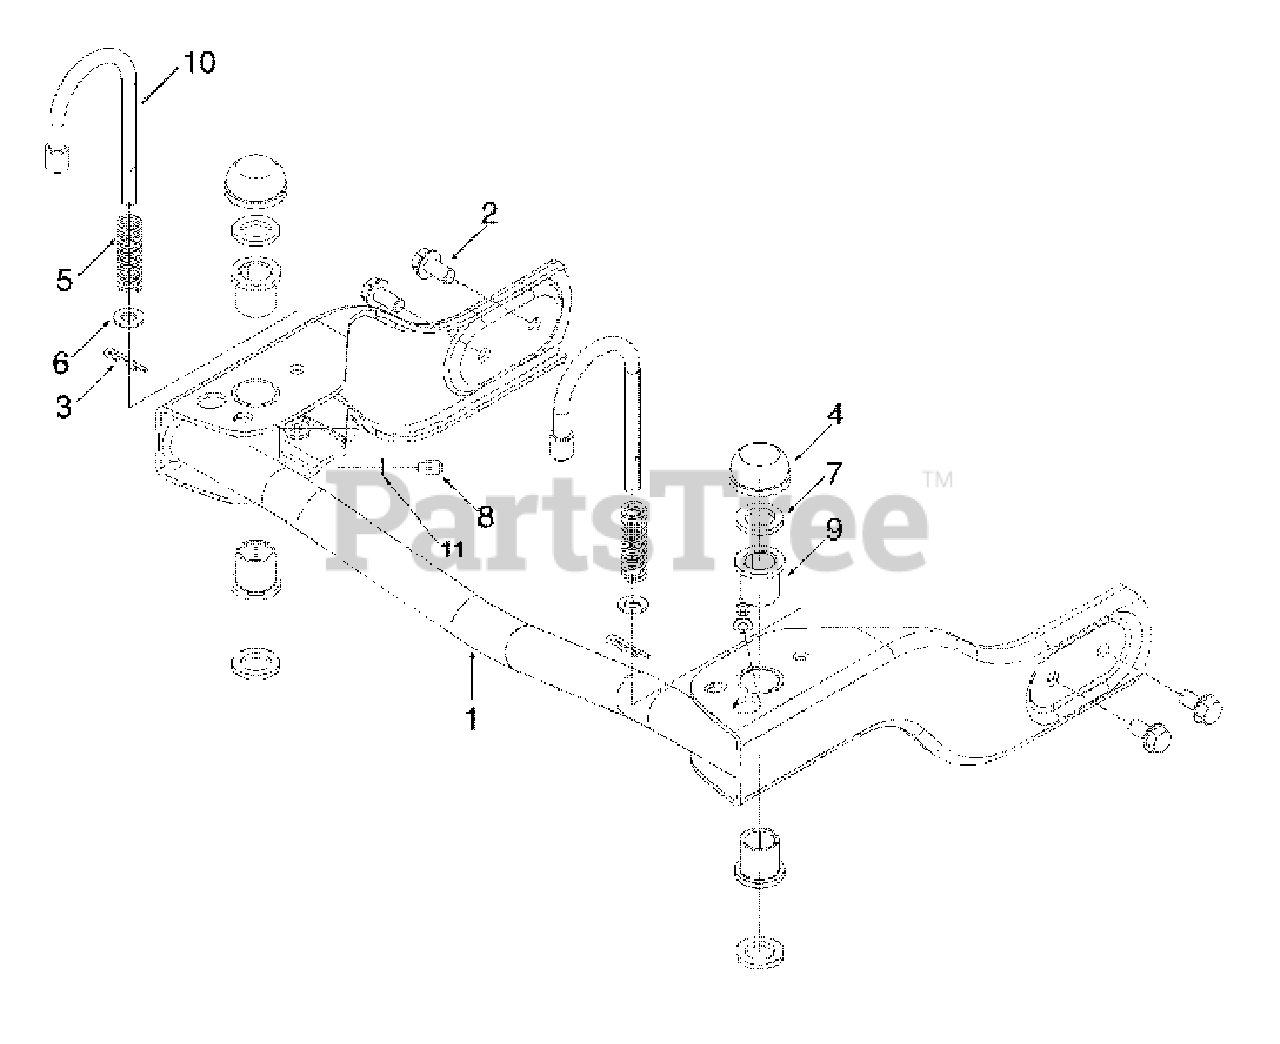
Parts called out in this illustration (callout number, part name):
1	Bracket Assembly, Front Wheel
2	Screw, Hex Wash. Hd. Tapp, 5/16-18 x .62
3	Pin, Internal Cotter
4	Cap, Push, 5/8
5	Spring, Compression
6	Washer, Flat, .330 x .630 x .06
7	Washer, Flat, .64 x 1.12 x .12
8	Fitting, Lube, 3/16
9	Bearing, Flange, .632 ID
10	Pin, Front Wheel Lock
11	Washer, Flat, .203 ID x .403 OD .040
